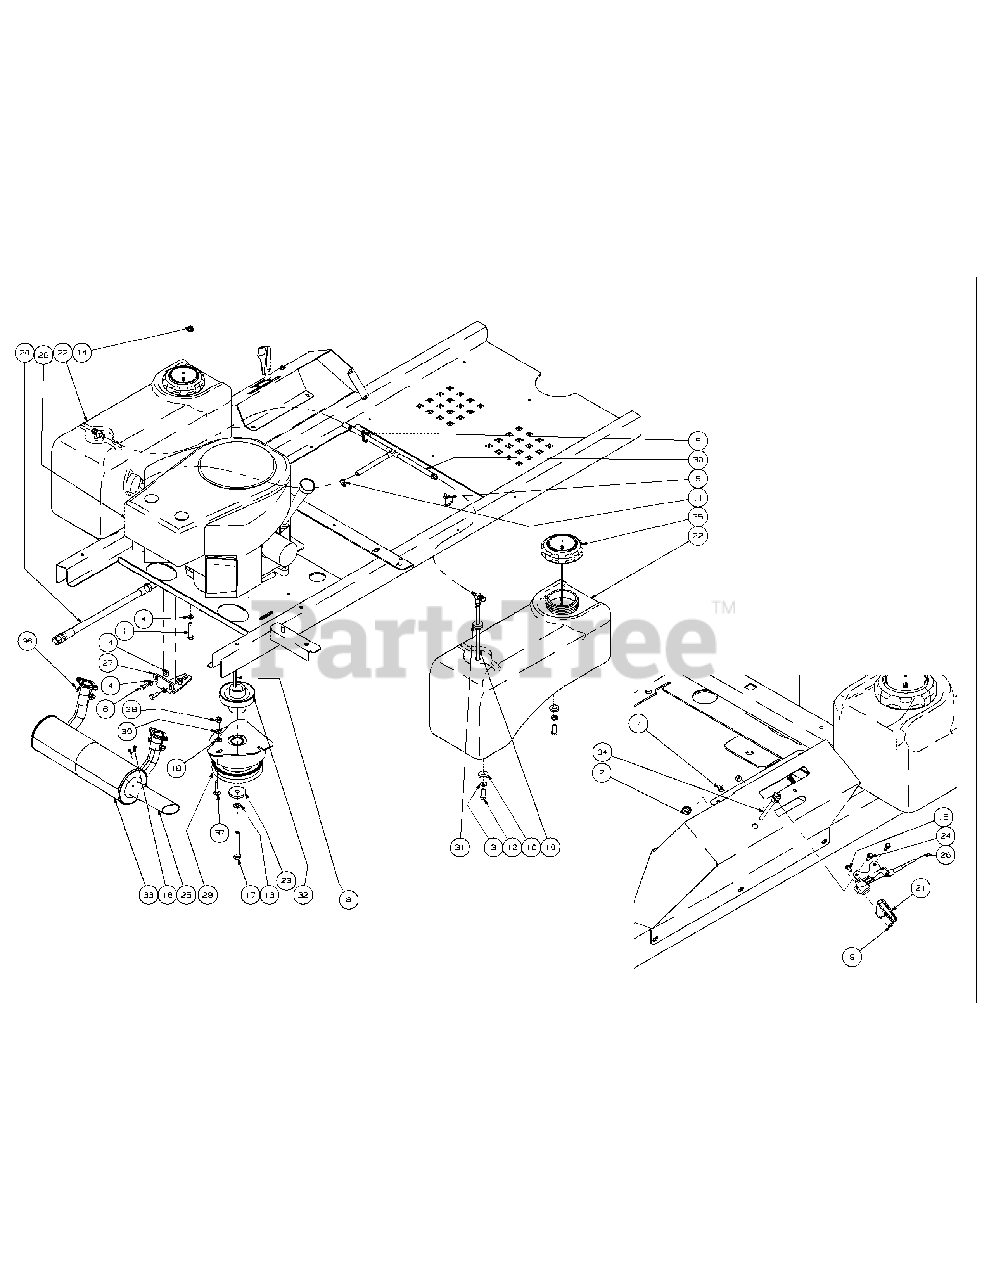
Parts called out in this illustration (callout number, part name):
1	HHCS, 5/16-18, 1-3/4
2	Jam Nut, 3/8-24
3	Lock Washer, 3/8 Zinc
4	Flat Washer, 5/16
5	Cable Tie, 3/16 x .05 x 7.4
6	Hex Cap Screw, 5/16-18 x .75
7	Lock Nut, Nylon Insert, 10-32
8	Key, .25 x .25 x 2.00
9	Nut, w/ Star Washer
10	Flat Washer, .390 x 1.00 x .180
11	Hose Clamp, SAE #4: 1/4-5/8, SS
12	Hex Cap Screw, 3/8-16 x .88
13	Lock Washer, 7/16
14	Lock Nut, Hex Flange, 5/16-18
15	Machine Screw, 8-32 x .375
16	Screw, 8-32 x .375, Hex Washer
17	Hex Cap Screw, 7/16-20 x 3.00
18	Washer, 3/8 x .738 x .063
19	Fuel Pickup Fitting
20	Oil Drain Extension Hose
21	Throttle Control Knob
22	Fuel Tank
23	Flat Washer, 7/16 ID x 1.75 OD x .250
24	Screw, #10-32 x 0.500
25	Exhaust Pipe
26	Throttle Control Cable
27	Clutch Retainer Assembly
28	23HP Kawasaki Engine
29	Electric Clutch
30	Fuel Hose Assembly includes:
30	Hose, 1/4" Fuel Line (70 inches)
31	Fuel Tank Groment
32	Transmission Drive Pulley
33	Kawasaki Muffler
34	Choke Cable
36	Nut, M8-1.25, Hex Flange
37	Carriage Bolt, 5/16-18 x 1.75
38	Hex Nut, 5/16-18
39	Lock Washer, 5/16
